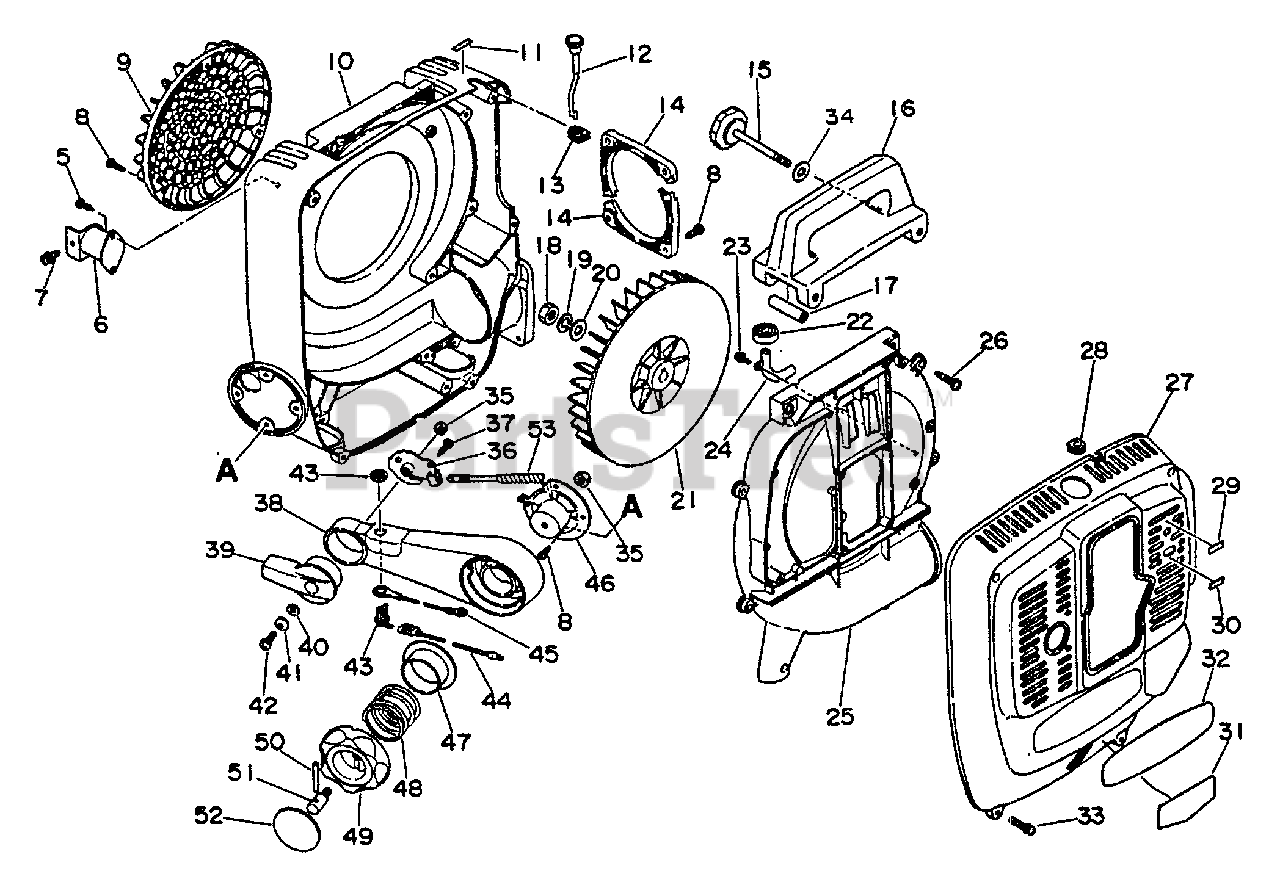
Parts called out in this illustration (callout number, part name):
5	SCREW - 5X12
7	SCREW - 5X12
8	SCREW - 5X12
9	GUARD, DEBRIS
10	COVER, FAN - INNER
11	LABEL - CHOKE
12	ROD, CHOKE
14	RETAINER
15	BOLT
18	NUT - 10
19	LOCKWASHER - 10
20	WASHER - 10
21	FAN
23	SCREW - 4X10
24	PIPE - INTAKE
25	COVER, FAN - OUTER
26	SCREW - 5X25
27	COVER
29	LABEL - IDLE
30	LABEL - CAUTION
31	LABEL - MODEL
32	LABEL - ECHO
33	SCREW - 5X20
34	WASHER - 6.5
35	LOCKNUT - 6
36	BRACKET, THROTTLE
37	SCREW - 4X10
38	MOUNT, THROTTLE LEVER
39	TRIGGER, THROTTLE
40	WASHER - 6
42	SCREW - 6X20
43	IGNITION SWITCH ASSY
44	LEAD - IGNITION
45	LEAD - GROUND
46	PLATE
47	SEAT, SPRING
52	LABEL - IDLE
53	WRAP, SPIRAL - 130mm
